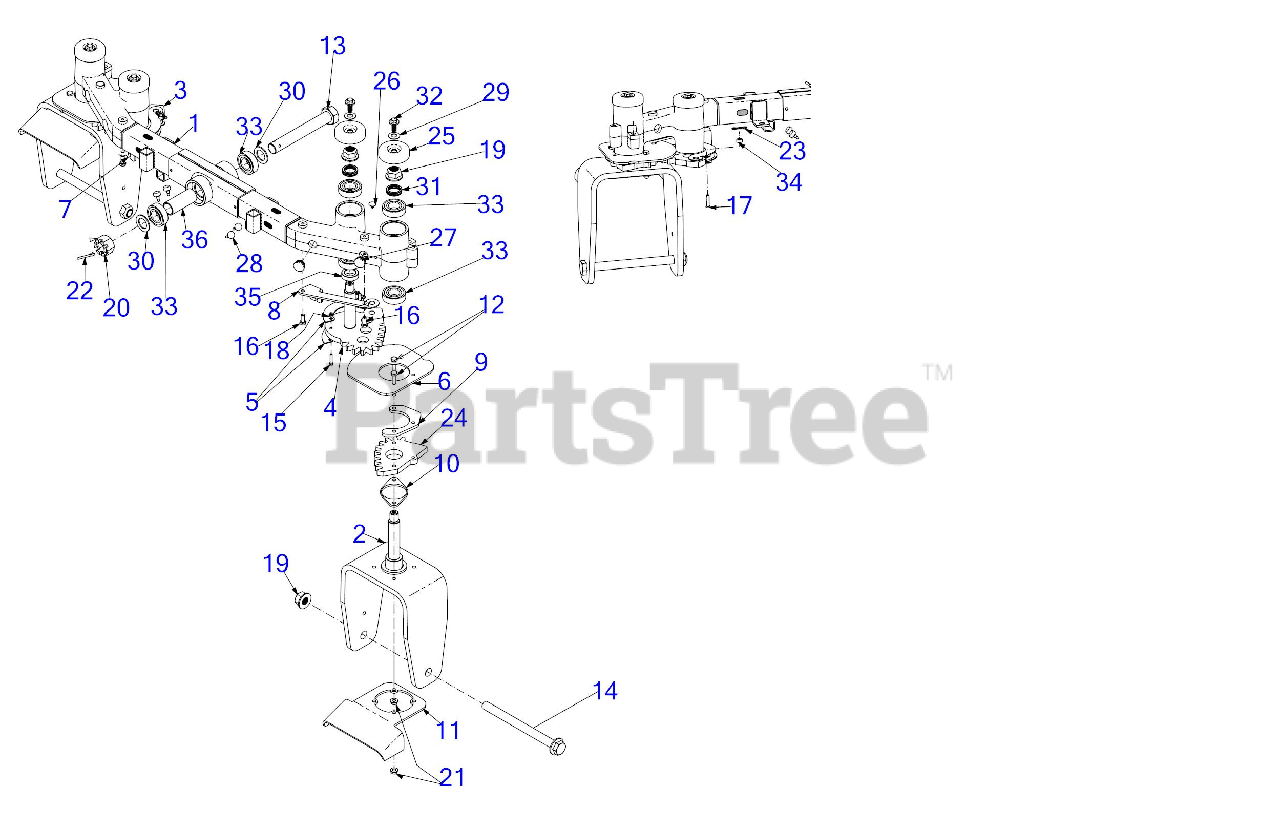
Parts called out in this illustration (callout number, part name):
4	RIGHT HAND STEERING GEAR ASSEMBLY
10	LOWER GEAR SPACER PLATE
12	HEX SCREW 5/16-18 x 2.25 GR5
13	HEX HEAD SCREW 1-14 X 7 GR5
14	SCREW 3/4-16 x 9.00 GR5
15	SCREW #10-24 x 1.00 GR5.1
16	SCREW 5/16-18 x .750
17	CLEVIS PIN .25 x 1.00
19	FLANGE LOCK NUT 3/4-16 TOP LOCK
20	CASTLE NUT 1.0-14 GR5
21	HEX FLANGE NUT
22	COTTER PIN
23	BOW TIE COTTER PIN 1/4-5/16
24	STEERING GEAR YOKE
25	AXLE CAP 2.5"
26	RATCHET CLIP
28	BUMPER, .62 DIA x .3
29	BELL WASHER
30	FLAT WASHER 1.031 X1.62 X.095
31	WAVE WASHER
33	BALL BEARING 1.0 X 52 X 15
36	SPACER 1.00 X 1.25 X 2.99
